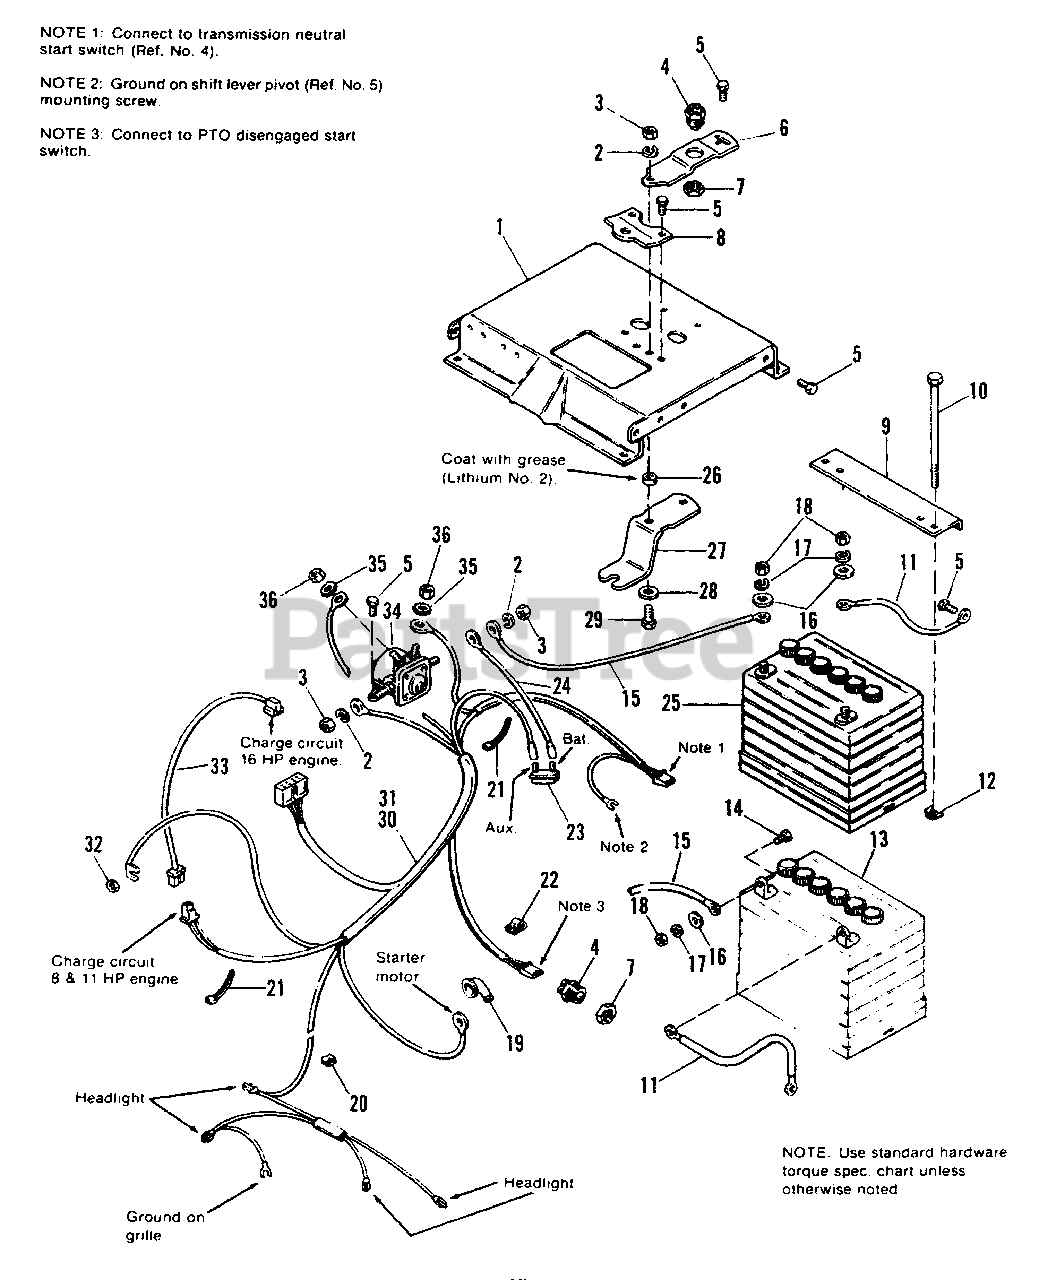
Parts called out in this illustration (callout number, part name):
1	SUPPORT, Frame
2	LOCKWASHER, 5/16
3	NUT, Hex, Full, 5/16-18
4	SWITCH, Interlock
5	SCREW, Hex, Taptite, 1/4-20 x 3/8
6	BRACKET, Switch
7	LOCKNUT Hex, 9/16-18
8	PIVOT, Shift Lever
9	HOLD DOWN, Battery
10	CAPSCREW, Hex, 1/4-20 x 7
12	NUT, Retainer, 1/4-20
13	BATTERY, 32 amp (Used on 6108 Only)
14	CAPSCREW, Hex, 1/4-20 x 3/4 (Used on 6108 Only)
16	WASHER, Plain, 1/4
17	LOCKWASHER, 1/4
18	NUT, Hex, Full, 1/4-20
19	COVER, Terminal
20	CLIP, Wire
21	TIE, Self Locking
22	CLIP, Speed
23	BREAKER, Circuit
25	BATTERY, 39 amp (used on 6111, 6116 & 6118)
27	LEVER, Switch
29	CAPSCREW, Hex, 5/16-18 x 1
30	HARNESS, Lower (Includes Ref. No. 31)
31	DIODE ASSY.
32	NUT, Hex, Mach., #8-32
33	WIRE ASSY. (Used on 6116 & 6118)
34	SOLENOID
35	LOCKWASHER, Ext. #10
36	NUT, Hex, #10-32
